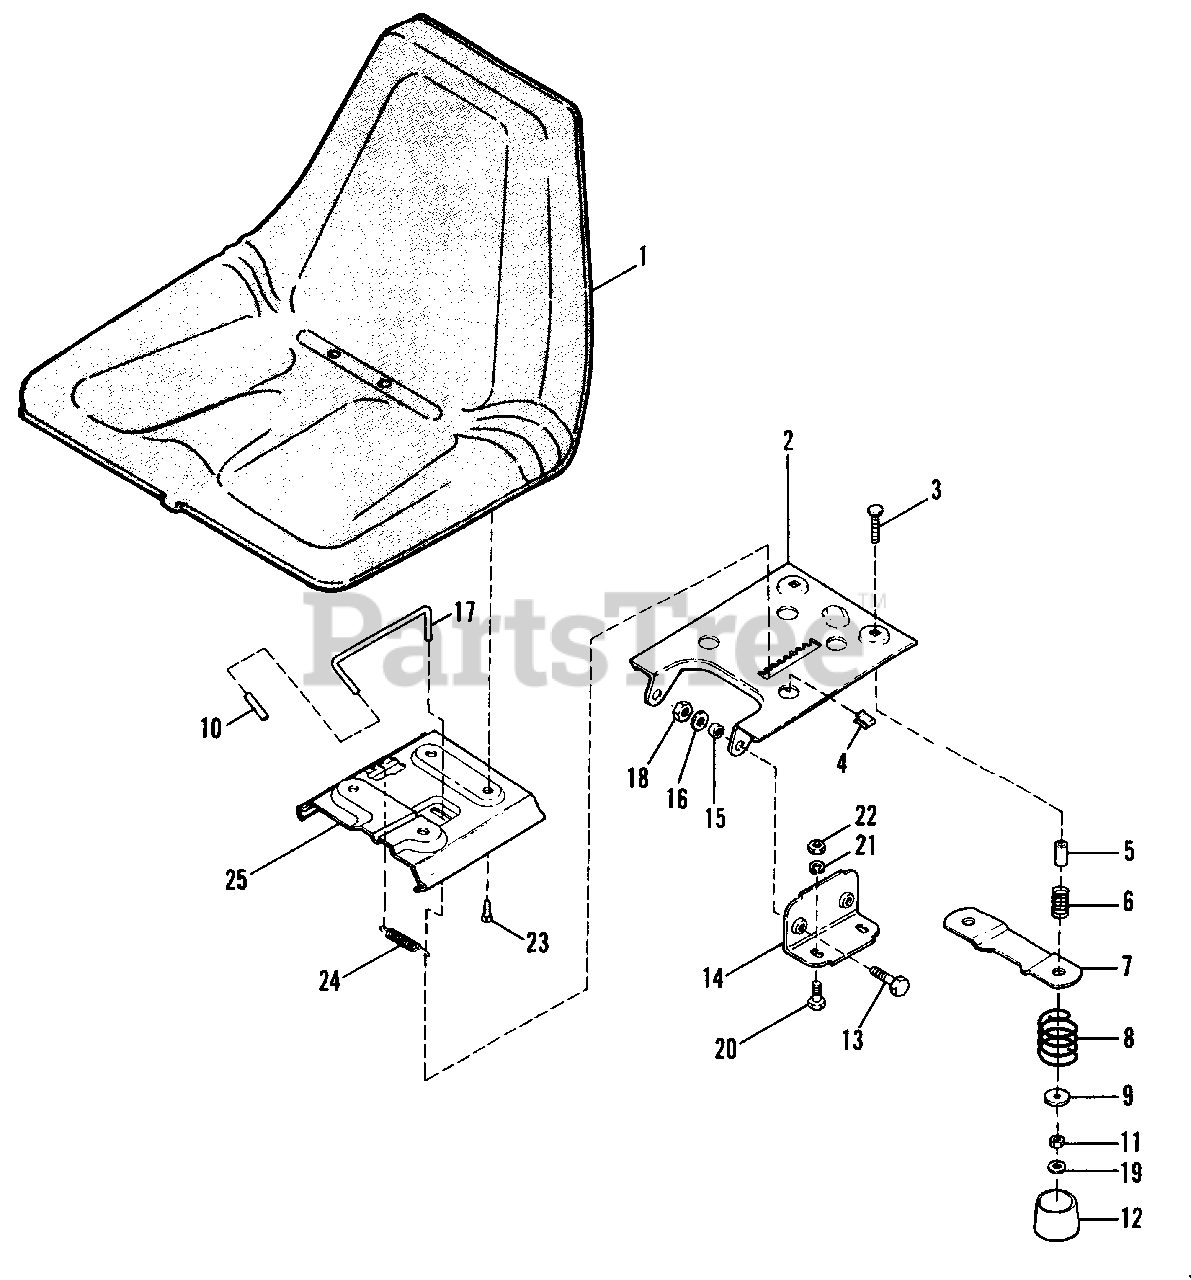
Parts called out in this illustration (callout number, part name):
2	SUPPORT, Seat, Pivot
3	CARRIAGE BOLT, 5/16-18 x 1-3/4
4	CLIP, Speed
6	SPRING, Compression
7	PLATE, Switch
8	SPRING, Compression, Seat
9	WASHER, Plain
10	HANDLE, Grip
11	NUT, Hex, Full, 5/16-18
12	COVER, Spring
13	CAPSCREW, 3/8-16 x 1-1/4
14	BRACKET, Seat, Suspension
16	WASHER, Plain 13/32
17	LEVER, Seat Release
18	NUT, Hex Hd., Nyloc, 3/8-16
19	WASHER, 1-1/32 x 1-7/8 x 1/16
20	CAPSCREW, Hex Hd., 5/16-18 x 3/4
21	LOCKWASHER, 5/16
22	NUT, Hex Full, 5/16-18
23	BOLT, Hex, Whizlock, 5/16-18 x 5/8
25	BRACKET, Seat Slide
